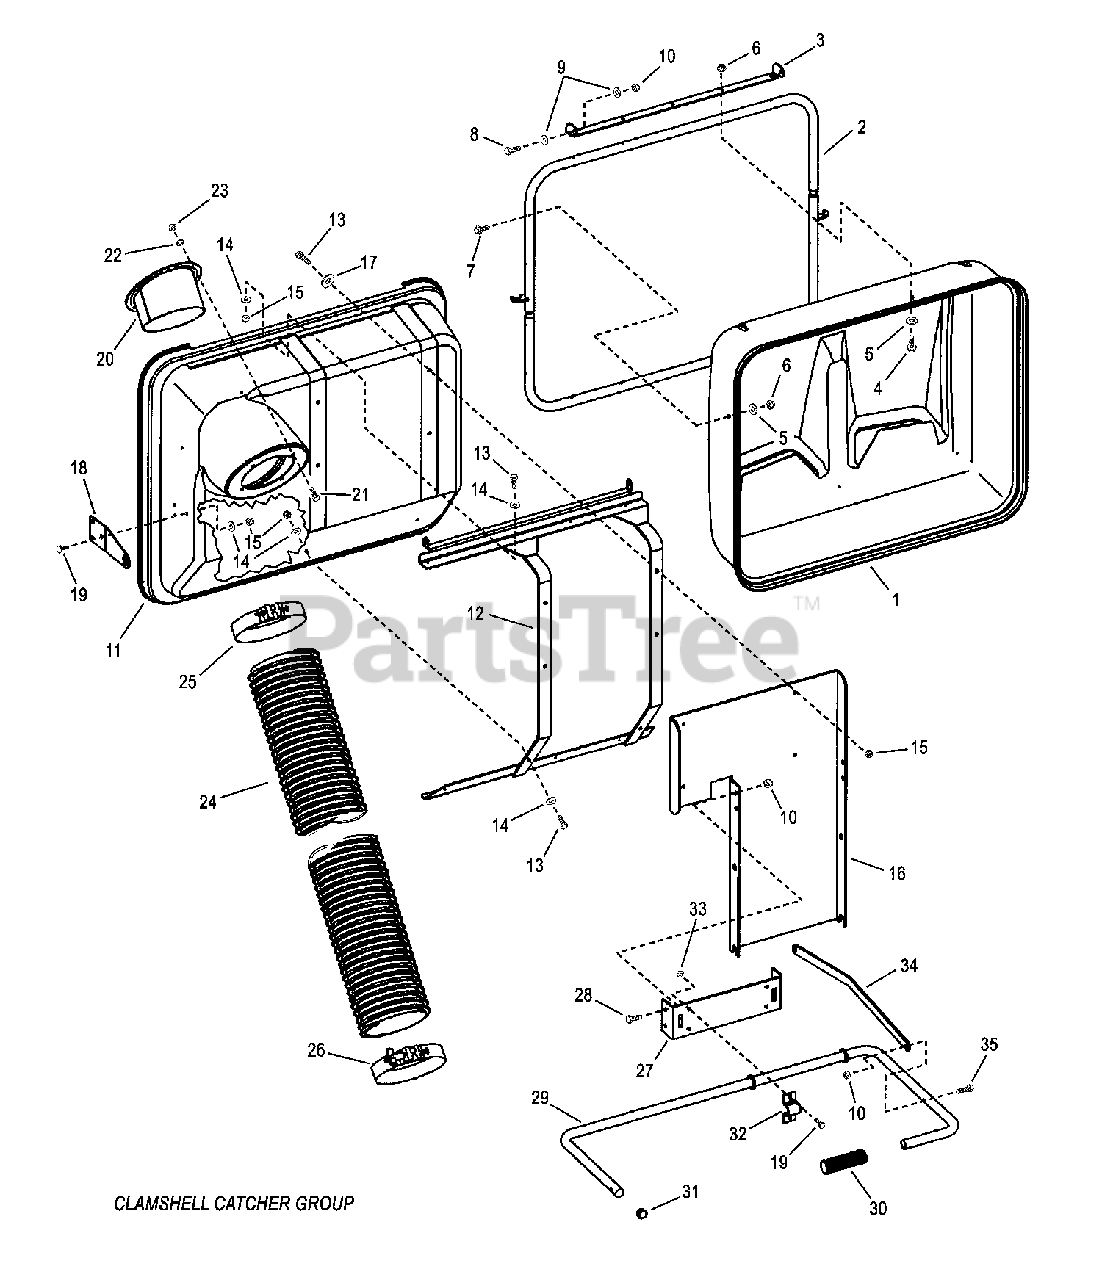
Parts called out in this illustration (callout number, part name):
1	COVER, Rear, Clamshell Bagger
2	WELDMENT, Rear Cover Brace
3	HINGE, Rear Cover
4	SCREW, #10-24 x 1-1/2 Hex Washer Machine
5	WASHER, .190 ID x .75 OD Flat
6	NUT, 10-24 Hex Flange Lock
7	BOLT, #10-24 x 1-1/2 Oval Head
8	SCREW, 3/8-16 x 1" Hex Head Cap, GR5
9	WASHER, 3/8" Flat
10	NUT, 3/8-16 Nyloc
11	COVER, Front, Clamshell Bagger
12	BRACE, Front Cover Weldment
13	SCREW, 5/16-18 x 1-1/4" Hex Head Cap, GR5
14	WASHER, .375 ID x .875 OD Flat
15	NUT, 5/16-18 Nyloc
16	MOUNT, Clamshell
17	WASHER, .33 ID x 1.25 OD Flat
18	HANDLE BRACE, Clamshell
19	BOLT, 5/16-18 x 1 Carriage
20	TUBE ADAPTER WELDMENT
21	SCREW, 1/4-20 x 1-1/4 Hex Head Cap, GR5
22	WASHER, 1/4 Split Lock
23	NUT, 1/4-20 Hex
24	HOSE, Snapper Fast Vac
25	HOSE CLAMP, Upper
26	HOSE CLAMP, Lower
27	BRACKET, Handle Mount
28	BOLT, 3/8-16 x 1 Hex Flange
29	HANDLE WELDMENT
30	GRIP
31	ENDCAP, Tube
32	BRACKET, Hanger
33	NUT, 5/16-18 Hex Flange Lock
34	ARM, Clamshell Actuating
35	SCREW, 3/8-16 x 2" Hex Head Cap, GR5
